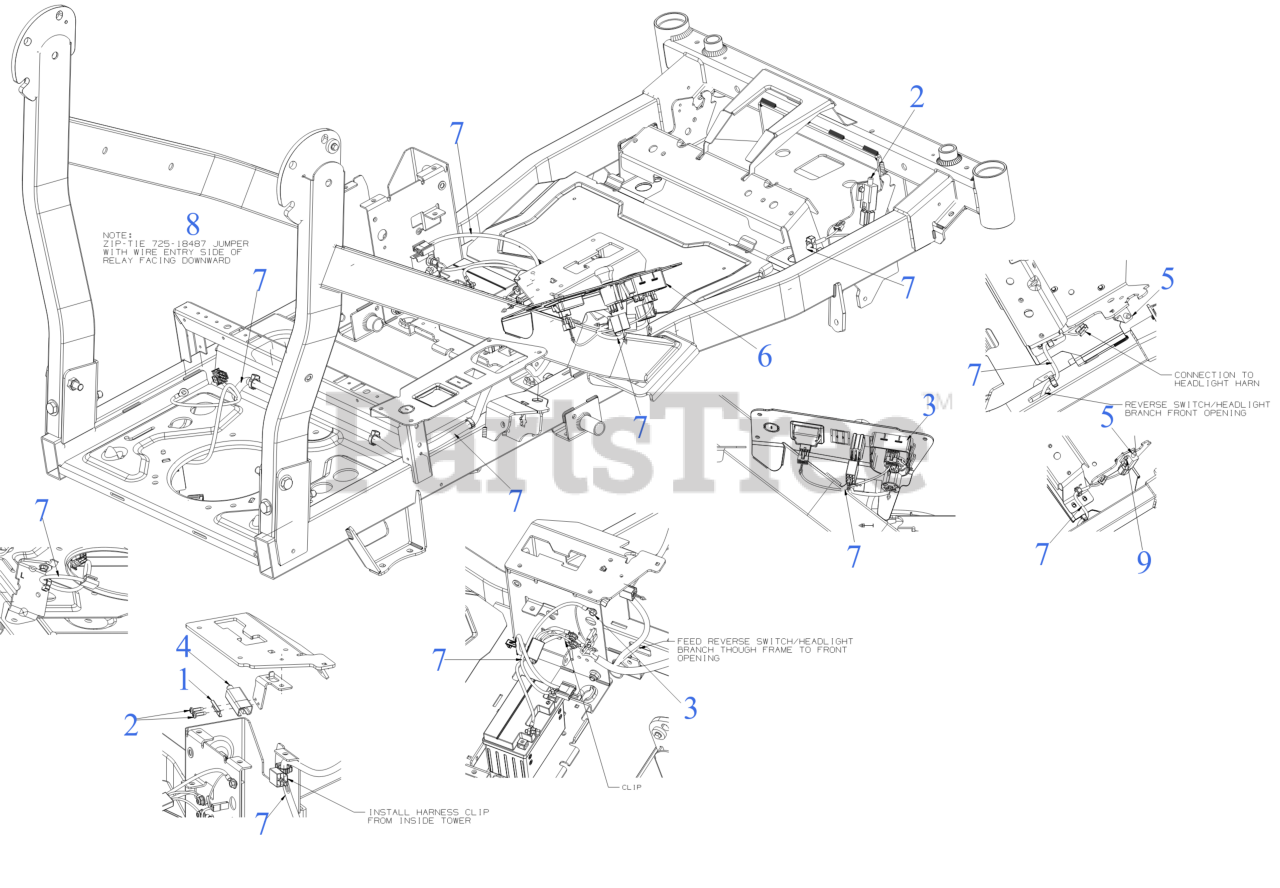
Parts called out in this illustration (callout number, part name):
1	PLATE-SWITCH
2	SCREW #10-24X11/16 T-25
3	SCREW 1/4-20X.625
4	SCREW MOUNT SWITCH NO/NC
5	INTERLOCK SWITCH (NO/NC)
6	IGNITION MODULE SWITCH (RMC ELC PTO WHTE)
7	MAIN HARNESS (KH-KT)
8	JUMPER HARNESS (KH-ZT)
9	SHOULDER SCREW
